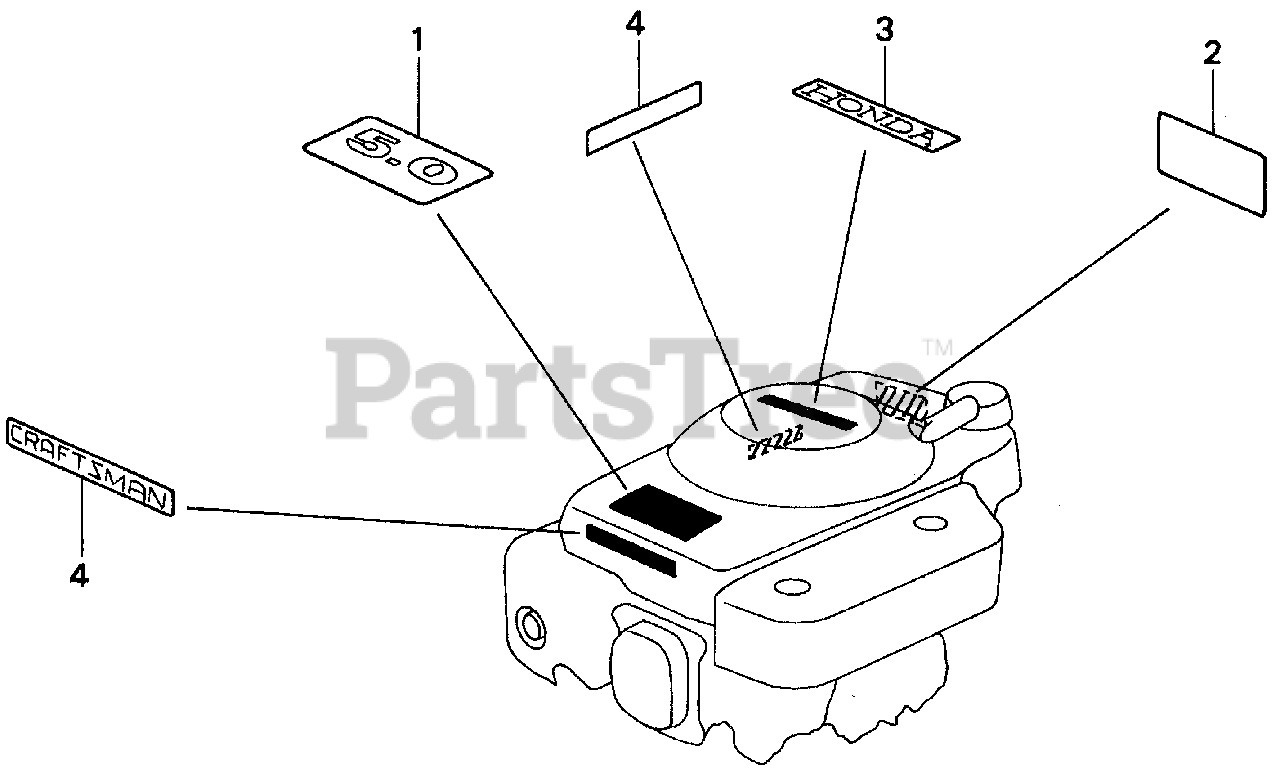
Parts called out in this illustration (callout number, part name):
1	MARK, EMBLEM (5.0)
2	MARK, OPERATOR CAUTION
5	MARK, EMBLEM (5.0)
